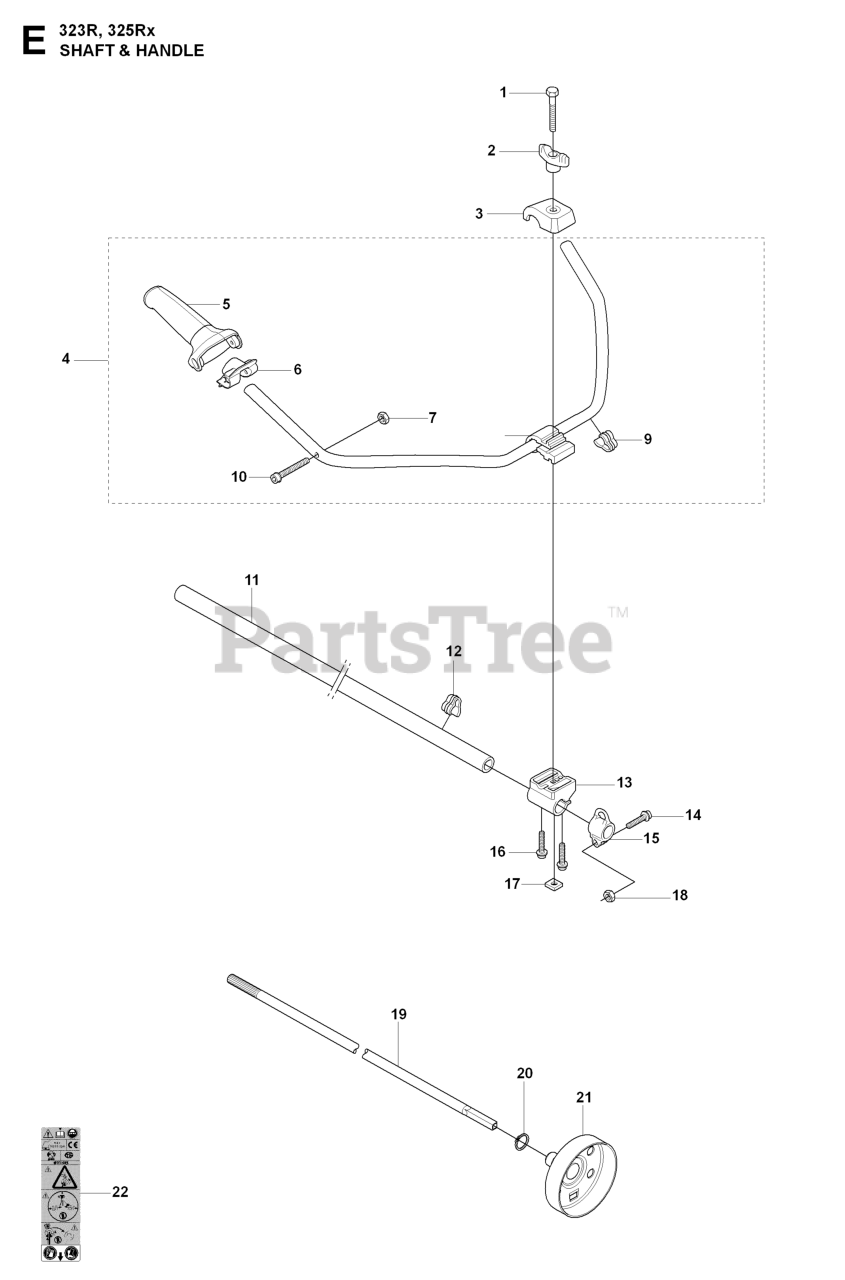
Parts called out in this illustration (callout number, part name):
8	HOLDER
11	DRIVE TUBE ASSEMBLY
14	SCREW
15	HARNESS HOLDER
19	DRIVE SHAFT
20	RETAINING RING SGA 10
21	CLUTCH DRUM
22	LABEL WARNING TRIMMERS AND BRU
